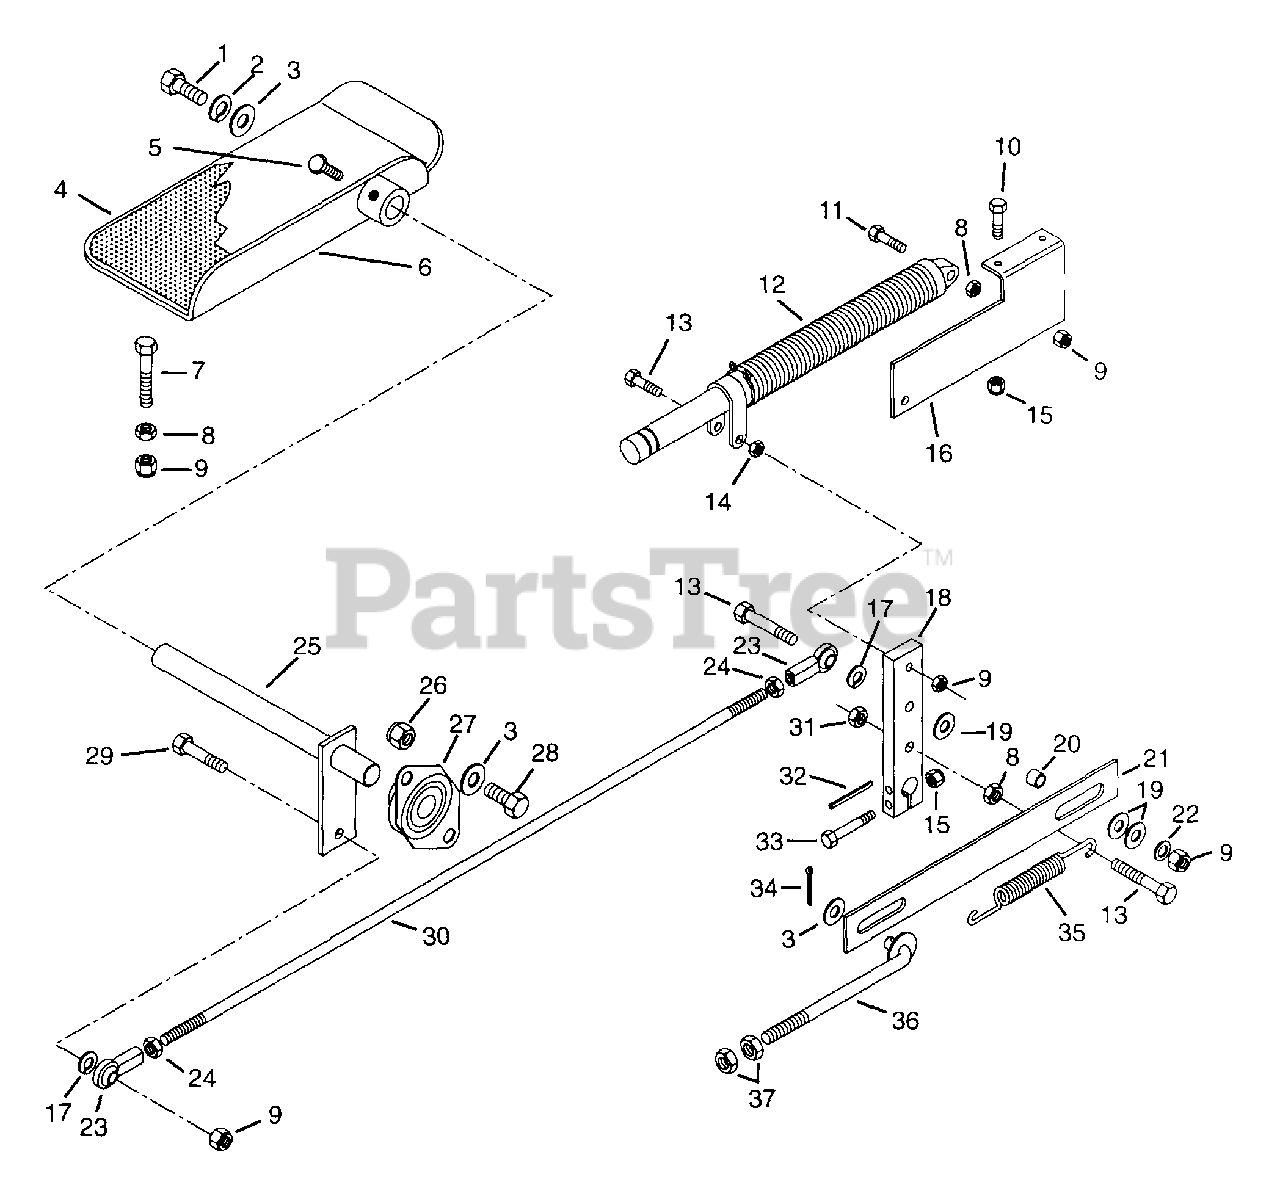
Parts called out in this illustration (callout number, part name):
1	Bolt-Hex .38-16 x 1.00 Grade 5
2	Washer-Lock .375 x .094
3	Washer-Flat - Steel .406 x .812 x .065
4	Cover, Large Footboard
5	Bolt-Hex .25-28 x .50
6	Weldment, Foot Control Lever
7	Bolt-Hex .31-18 x 2.50 Grade 5
8	Nut-Hex .312-18 Grade 2
9	Nut-Locking-Nylon .312-18 Grade 2
10	Bolt-Hex .25-20 x .63
11	Bolt-Hex .31-18 x 1.75 Grade 5
12	Damper
13	Bolt-Hex .31-18 x 2.00 Grade 5
14	Nut-Jam .312-18
15	Nut-Locking-Nylon .250-20 Grade 2
16	Bracket, Damper
17	Washer-Lock .313 x .078
18	Arm, Pump
19	Washer-Flat-Steel .531 x 1.062 x .095
20	Bushing, Steel .328 x .500 x .500
21	Strap, Neutral Detent
22	Washer-Flat-Steel .344 x .688 x .065
23	Rod End, 5/16" Female
24	Nut-Jam .312-24
25	Weldment, Control
26	Nut-Locking-Nylon .375-16 Grade 2
27	Bearing-Flange .75 x 2 Holes x 2.123
28	Bolt-Hex .38-16 x .75 Grade 5
29	Bolt-Hex .31-18 x 1.25 Grade 5
30	Rod, Speed Control
31	Nut-Locking-Center .312-18 Grade 2
32	Pin-Roll .250 x 1.000
33	Bolt-Hex .25-20 x 1.75 Grade 2
34	Pin-Cotter .09 x .75
35	Spring-Tension .091 x .500 x 5.50
36	Weldment, Detent Rod
37	Nut-Hex .375-24 Grade 2
